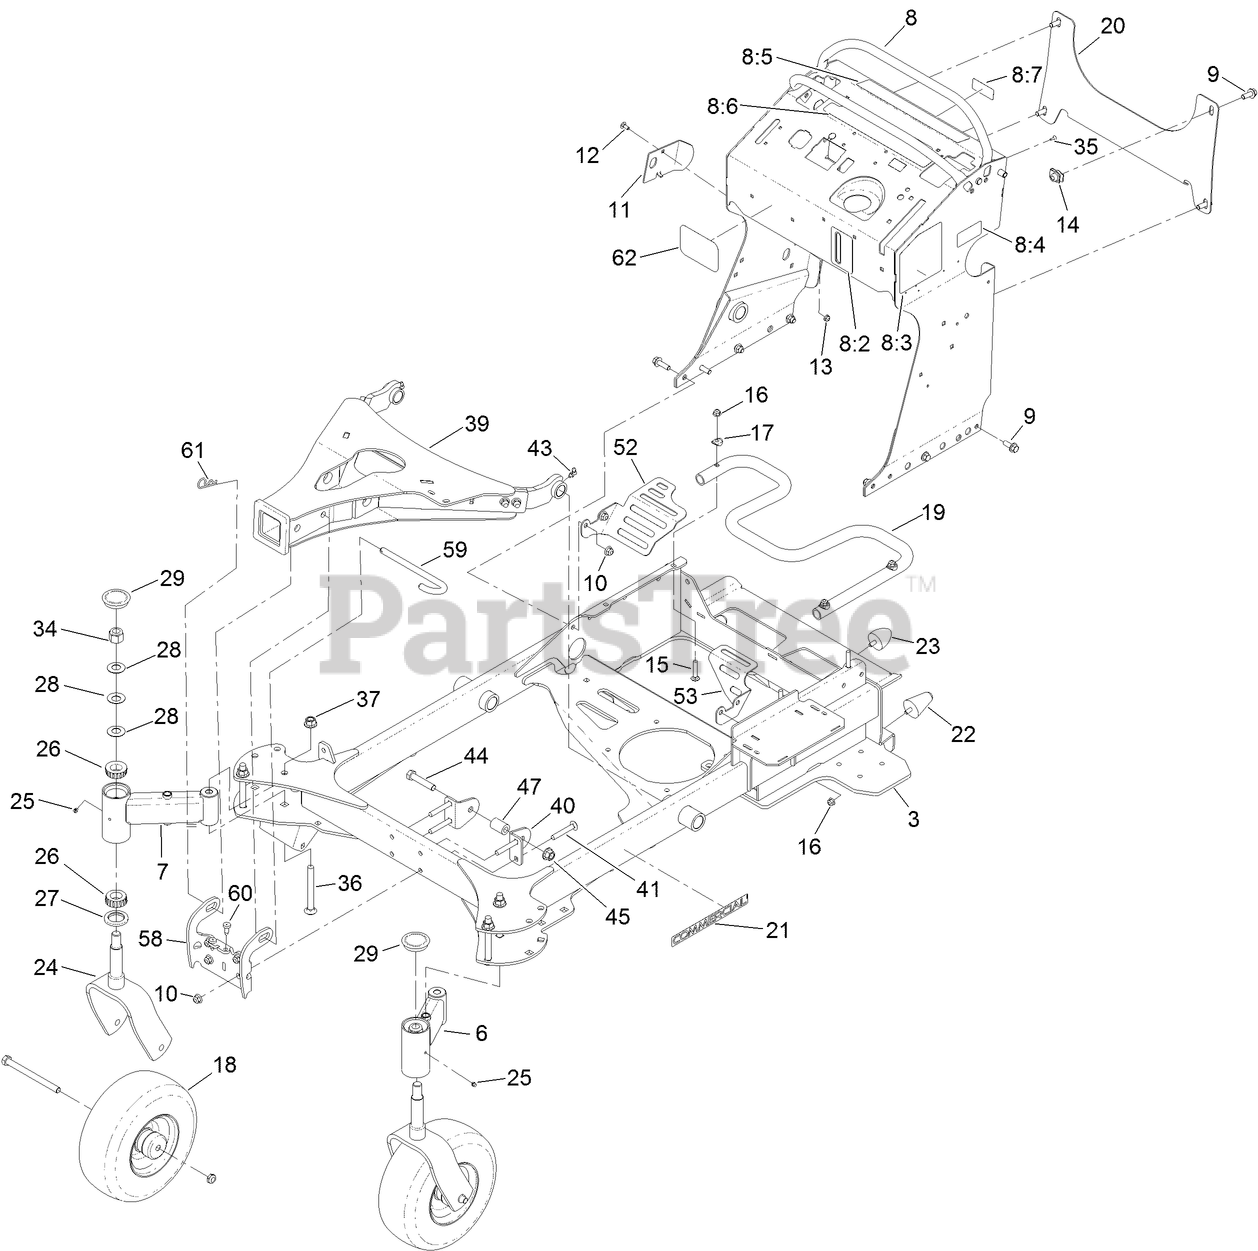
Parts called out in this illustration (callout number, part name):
6	TUBE CASTOR SHORT
7	TUBE CASTOR LONG
8	TOWER DECAL ASM
8:2	DECAL-LEVEL, OIL
8:3	DECAL-SERVICE AID
8:4	DECAL-FILL, FUEL
8:5	OBS DECAL-CAUTION
8:6	DECAL-CONTROLS
8:7	DECAL-FUSE
9	SCREW-HHF
10	NUT-HF, NI
11	PLATE-STRIKER
12	SCREW-CARR
13	NUT-HF
14	Nut-Tinnerman
15	SCREW-CARR
16	NUT-HF, NI
17	WASHER
18	WHEEL/TIRE AND BEARING ASM
19	TUBE-MOUNT, FUEL TANK
20	BRACKET-CROSS
21	DECAL-COMMERCIAL
22	BUMPER-RUBBER
23	BUMPER-RUBBER
24	FORK-CASTER
26	BEARING-ROLLER, TAPERED
27	SEAL-GREASE
28	WASHER-BELLVILLE
29	CAP-GREASE
34	NUT-LOCK, NI
35	RIVET-POP
36	SCREW-CARR
37	NUT-LOCK
39	A-FRAME ASM
40	BRACKET-CYLINDER
41	SCREW-CARR
43	FITTING-GREASE, 90 DEG
44	SCREW-HH
45	NUT-LOCK
47	SPACER
52	GUARD-FAN, RH
53	GUARD-FAN, LH
58	BRACKET-LOCK
59	PIN-HITCH
60	BUMPER-RUBBER
61	PIN-HAIR
62	DECAL-LOGO, TORO
